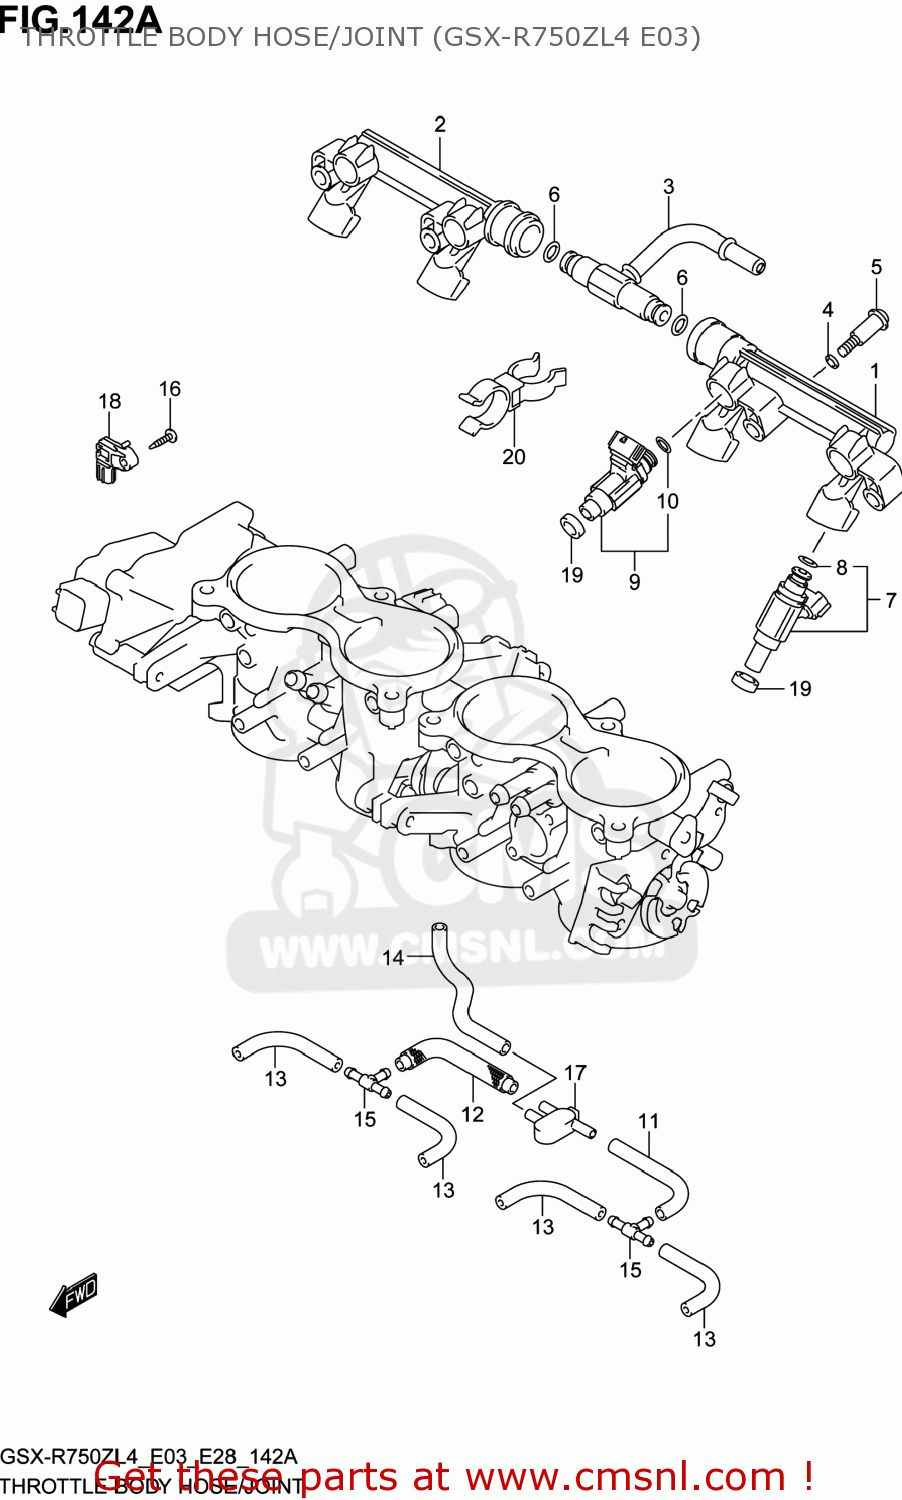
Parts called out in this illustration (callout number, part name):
1	DELIVERY PIPE
2	DELIVERY PIPE
3	NIPPLE ASSY
4	PACKING (NAS)
5	SCREW
6	O RING
7	INJECTOR ASSY
8	O-RING
9	INJECTOR ASSY
10	O-RING
11	HOSE
12	HOSE
13	HOSE(L:425)
14	HOSE
15	3WAY,VACUUM HOSE
16	SCREW
17	JOINT
18	SENSOR,BOOST
19	SEAL
20	CLAMP
